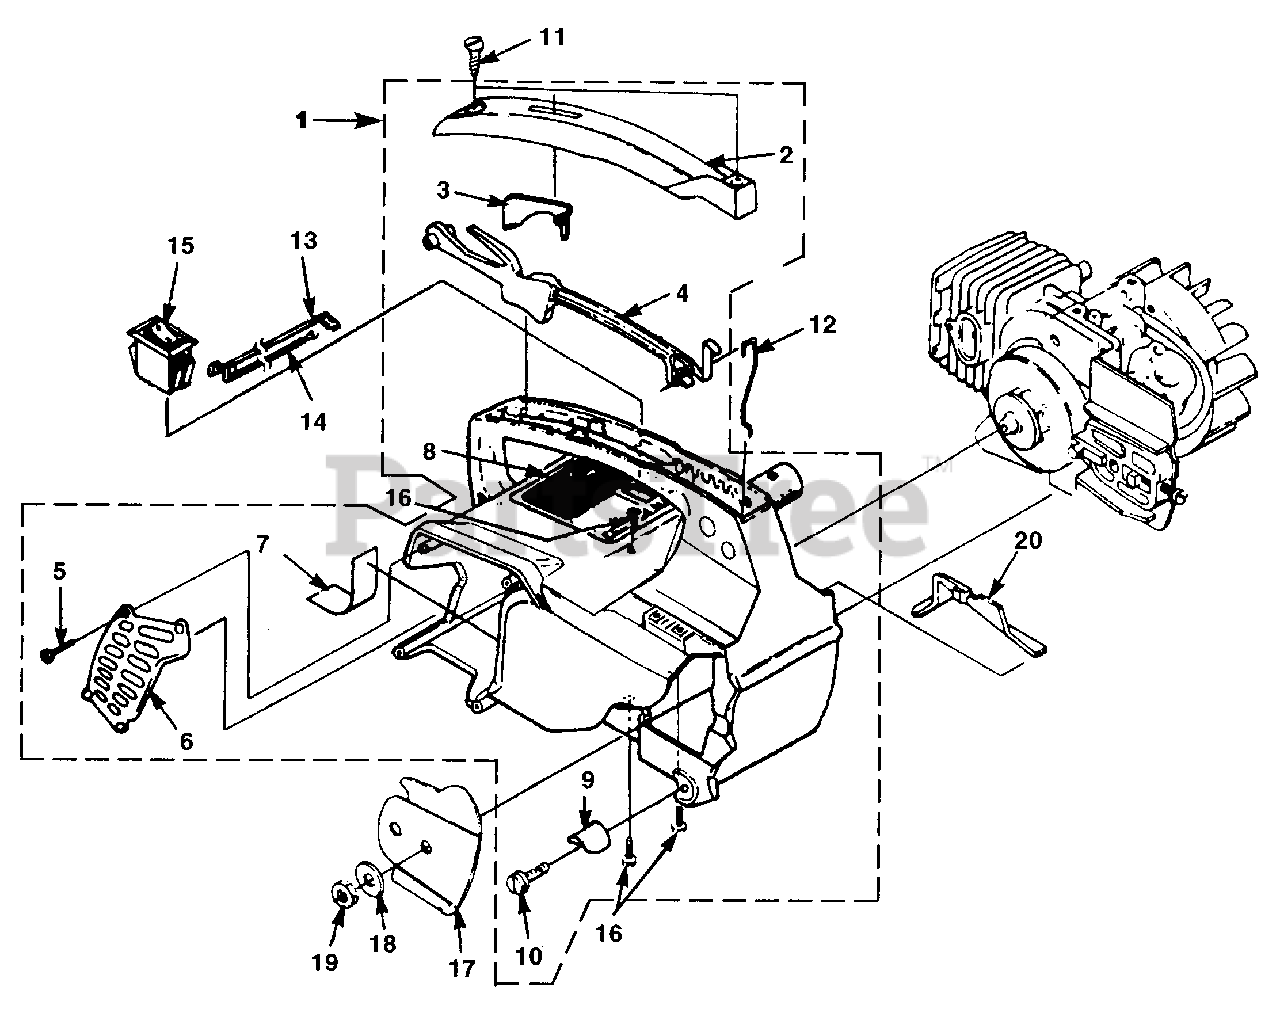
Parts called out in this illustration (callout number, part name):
1	ENGINE HOUSING KIT
2	COVER - Handle
3	LOCK - Trigger
4	TRIGGER
5	SCREW - Pan, plastite (#6 X 3/8")
6	SHIELD - Muffler
7	TAPE
8	DECAL - Warning
9	STOP - Chain
10	SCREW - Torx, plastite (#10 X 3/4")
11	SCREW - Pan, plastite (#10-16 X 3/4")
12	ROD - Throttle
13	LEAD - w/Flag Term.
14	LEAD - w/Ring Term.
15	SWITCH
16	SCREW - Torx, taptite (10-24 X 3/4")
17	PLATE - Guide Bar
18	WASHER - Flat
19	NUT - Hex
20	COVER - AIR Filter
